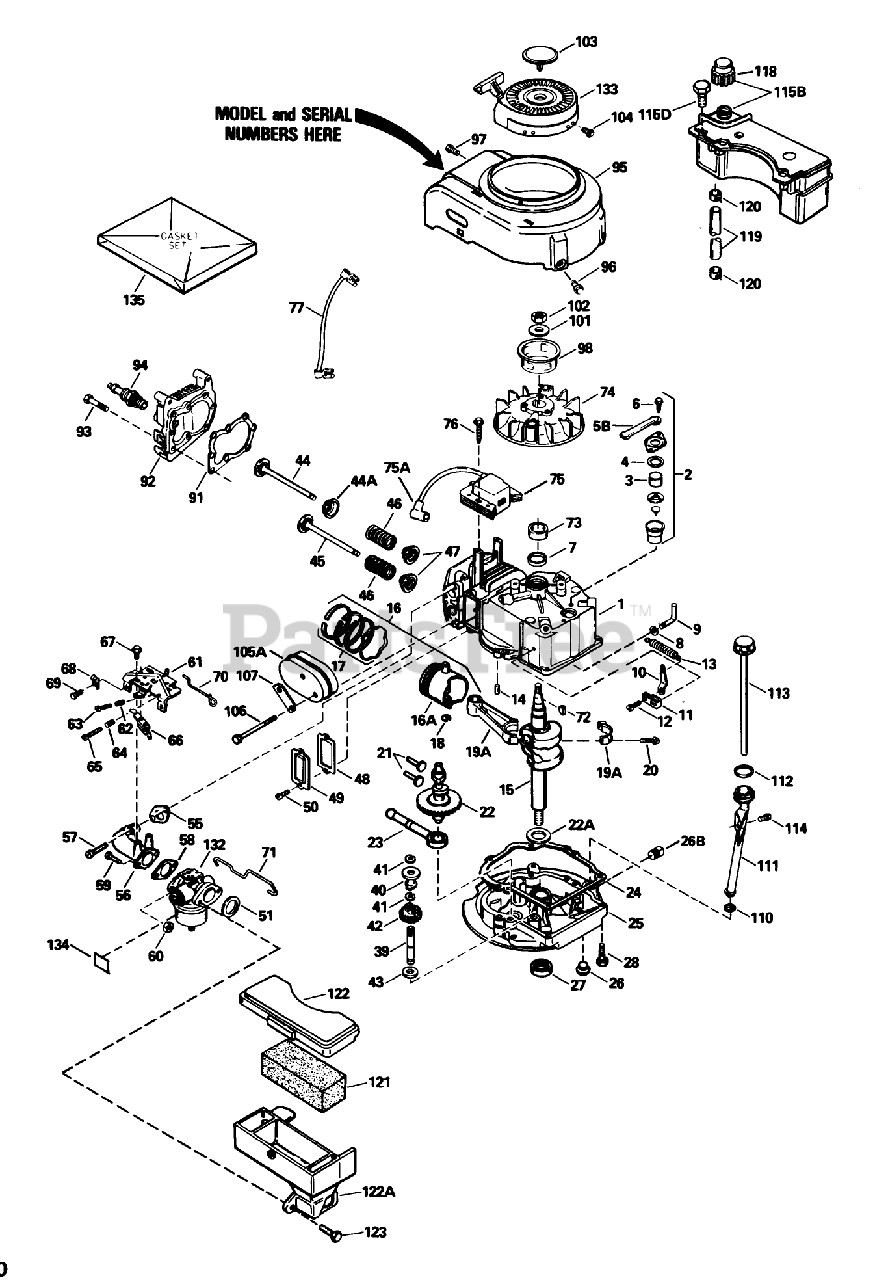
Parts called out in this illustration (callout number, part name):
1	Cylinder Assembly (Incl. Ref. #7 14)
2	Breather Assy. (Incl. Ref. #46 thru 51)
3	Element-Breather
4	Gasket-Breather
5B	Tube, Breaker
6	Screw (10-24 x 9/16)
7	Seal-Oil
8	Washer-Flat
9	Rod, Governor (Incl. No. 36)
10	Governor Lever
11	Clamp-Lever, Governor
12	Screw
13	Spring Governor
14	Pin-Dowel
15	Crankshaft Assembly
16	Piston-Pin Ring Assy. (Std.)(Incl. Ref. #16A, 17 18)
16	Piston-Pin Ring Assembly (.010 oversize)(Incl. Ref. #16A, 17 18)
16	Piston, Pin Ring Assy. (.020 Oversize)(Incl. Ref. #13A, 14, 15)
16A	Piston Pin Assy. (Std.)(Incl. Ref. #14)
16A	Piston Pin Assembly (.010 oversize)(Incl. Ref. #18)
16A	Piston Pin Assy. (.020 Oversize) (Incl. Ref. #14)
17	Ring Set-Piston (Std.)
17	Ring Set, Piston(.0100versize)
17	Ring Set (.020" OS)
18	Ring-Retaining, Piston Pin
19A	Rod Assembly, Connecting (Incl. Nos. 17 18)
20	Bolt-Rod, Connecting
21	Lifter-Valve
22	Camshaft(Mech.Comp. Release)
22A	Washer-Thrust
23	Oil Pump ASM
24	Gasket
25	Flange-Mounting (Incl. Ref. #26, 27 39)
26	Plug Oil Drain
26B	Plug-Pipe
27	Seal-Oil
28	Screw (1/4-20 x 1-1/4)
39	Shaft-Governor
40	Spool-Governor
41	Ring-Retaining
42	Governor Gear ASM
43	Washer
44	Valve, Intake (Std.) (Incl. Ref. #40)
44	Valve, Intake (1/32" oversize)(Incl. No. 40)
44A	Seal Assy., Intake
45	Valve, Exhaust (Std.)(Incl. No. 40)
45	Valve, Intake (1/32" oversize)(Incl. No. 40)
46	Spring-Valve
47	Cap-Valve, Spring
48	Gasket-Cover, Valve
49	Cover-Valve
50	Screw
51	Gasket-Cleaner, Air
55	Gasket-Intake Pipe
56	Pipe-Intake (Incl. Ref. #59)
57	Screw (1/4-20 x 1)
58	Gasket
60	Nut and Lock Washer (1/4-28)
61	Control Assy.-Remote Speed (Incl. Ref. #69 thru 72 76)
62	61709/GIL1515A/95-5
63	Screw
64	Spring-Compression
65	Screw
66	Terminal
67	Screw (10-24 x 9/16)
68	Conduit
69	Screw (10-32 x 3/8)
70	2035A67 ADD.ASSEMBL
71	Link-Throttle
72	Key-Flywheel
73	Spacer
74	Flywheel
75	Solid State
75A	Cover-Spark Plug
76	Screw
77	Wire-Ground
91	Gasket-Cylinder Head
92	Head-Cylinder
93	Screw (5/16-18x1-1/2)
94	Spark Plug-Resistor (R J19 L M)
95	Housing-Blower
96	Screw (1/4-20 x 1/2)
97	Screw (10-24 x 9/16)
98	Hub-Starter
101	Washer-Belleville
102	Nut-Flywheel
103	Plug Starter
104	Screw, Hex Hd.
105A	Muffler
106	Screw
107	Plate-Lock
110	Gasket
111	Oil Fill Tube
112	O-Ring
113	Dipstick
114	Screw (10-32 x 1/2)
115B	Tank Assembly-Fuel (Incl. Ref. #102)
115D	Screw (10-32 x 35/64)
118	Cap-Fuel
119	Line-Fuel
120	Clamp-Line, Fuel
121	Filter-Air Cleaner
122	Cover-Air Cleaner
122A	Body Air cleaner
123	Screw
132	Carburetor (Incl. Ref. #58)
133	Starter-Rewind
134	Decal-Primer
135	Gasket Set (Incl. Items Marked *)
